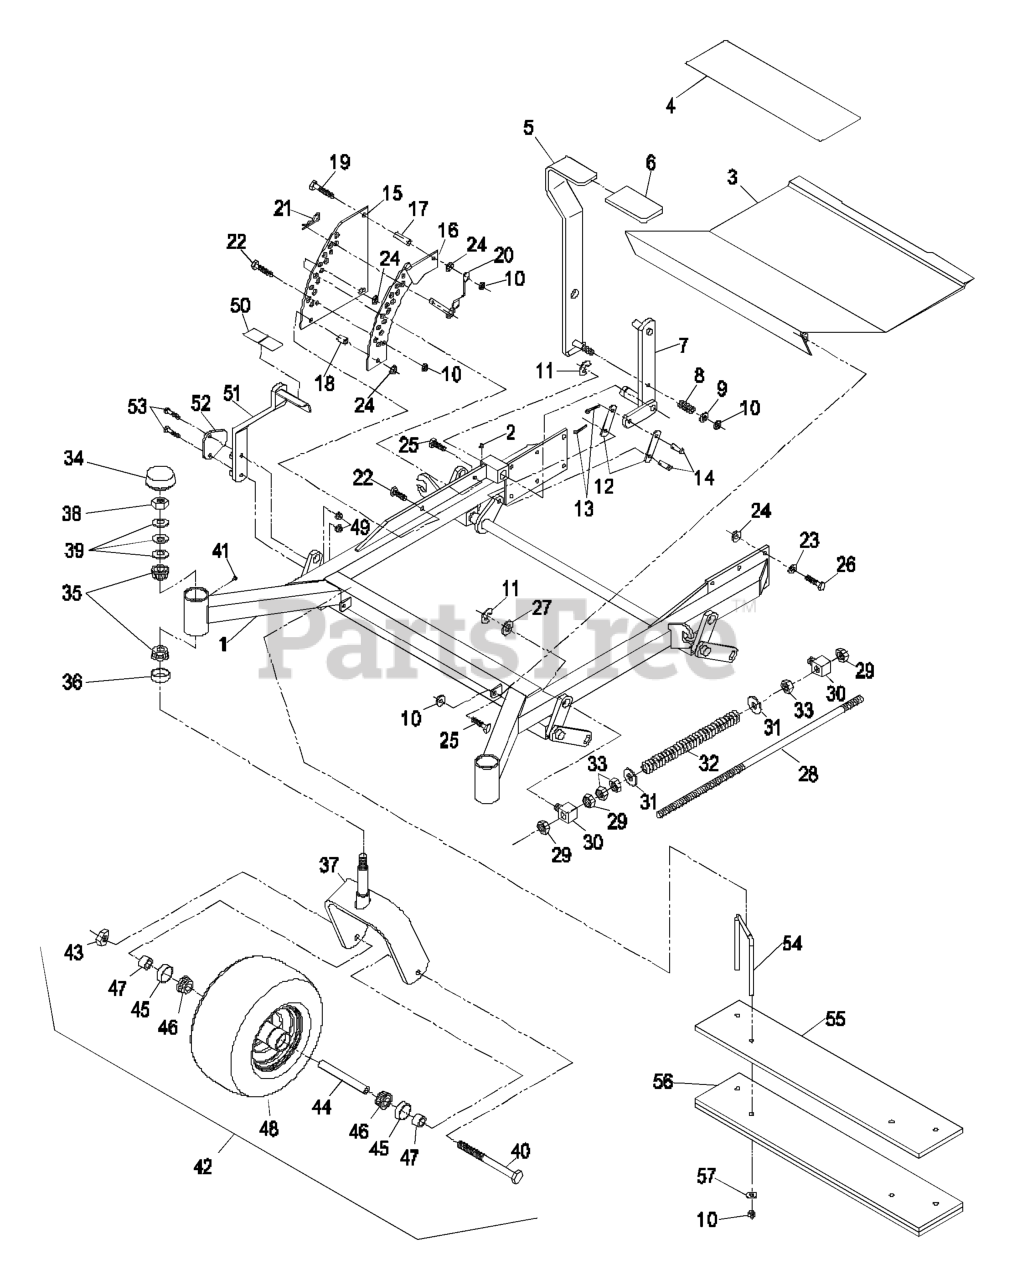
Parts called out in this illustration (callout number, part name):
2	FITTING-GREASE
4	PAD-ANTISKID
6	GRIP-LEVER, LIFT
8	SPRING-COMPRESSION
9	WASHER-FLAT
10	NUT-LOCK, NI
11	RING-RETAINING, EXT
12	ARM-LIFT, DECK
13	PIN-COTTER
14	PIN-CLEVIS
15	PLATE-LIFT, DECK
16	PLATE-LIFT, DECK
17	BUSHING-LEVER, LIFT
18	BUSHING-LEVER, LIFT
19	SCREW-HH
20	PIN-HITCH (W/LANYARD)
21	PIN-COTTER
22	SCREW-HH
23	WASHER-BELLEVILLE
24	NUT-HHF, WHIZ
25	SCREW-HH
26	SCREW-HH
27	WASHER-FLAT
28	ROD-LIFT, DECK
29	NUT-HEX
30	SWIVEL-DECK MOUNT, REAR
31	WASHER-FLAT
32	SPRING-SUPPORT, DECK
33	NUT-JAM
34	CAP-GREASE
35	Cone-Bearing Tapered Roller
36	SEAL-GREASE
38	NUT-LOCK, NI
39	WASHER-BELLVILLE
40	SCREW-HH
43	NUT-HEX
44	SPACER-CASTER, FRONT
45	SEAL-CASTER
46	BEARING-CONE, TAPERED ROLLER
47	SPACER-BEARING
51	LEVER,DECK LIFT WLD
53	SCREW-HH
54	U-BOLT, ZC
56	WEIGHT BAR ASM
57	WASHER-FLAT
